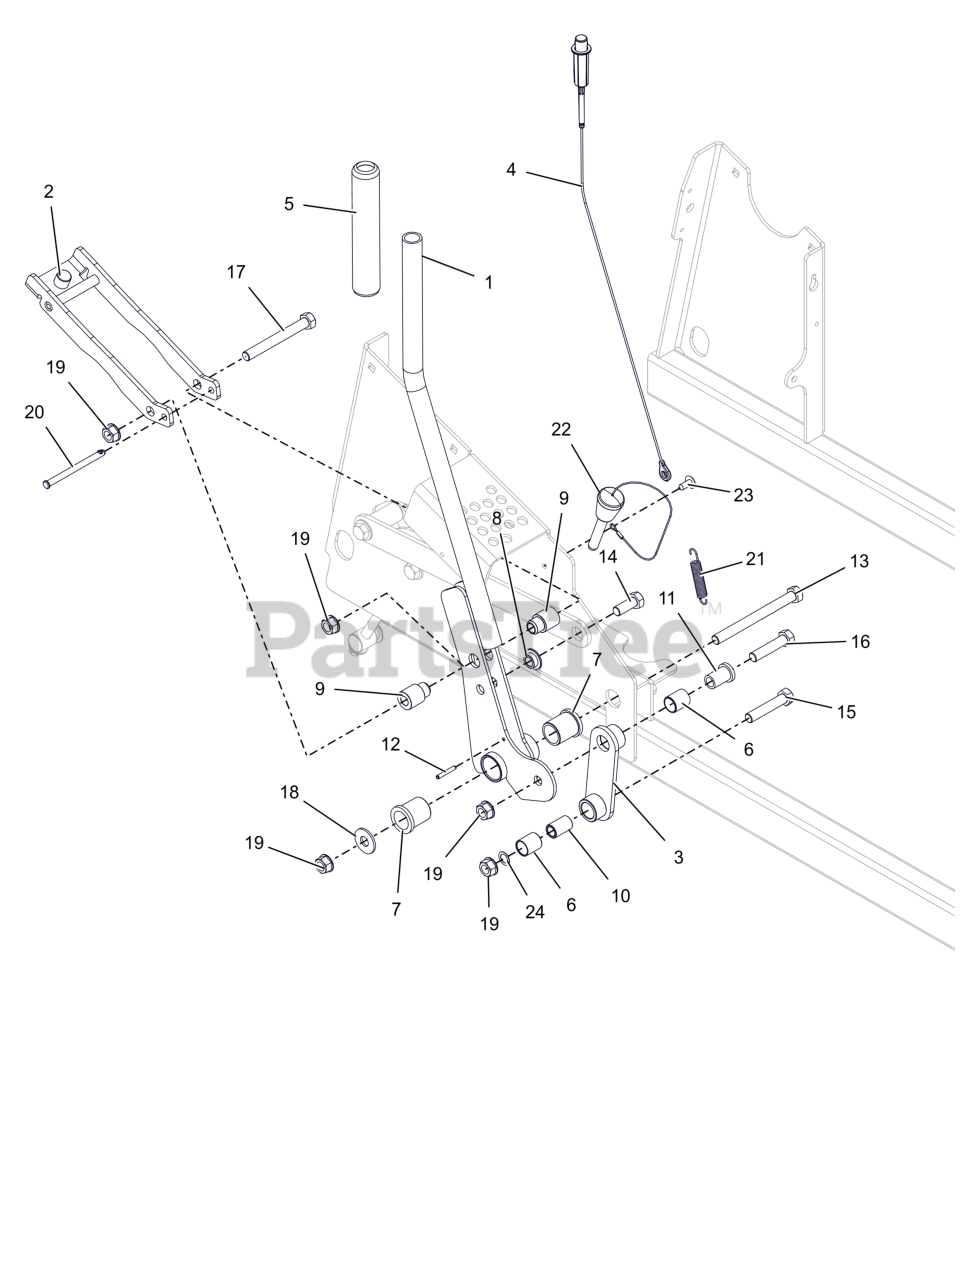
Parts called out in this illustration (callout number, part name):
1	WLDMT, HOC LEVER
2	WLDMT, HOC BRACKET
3	LINK, HOC LEVER
4	CABLE, HOC PUSH CONTROL
5	GRIP, DECK LIFT
6	BRG, .750 X .875 X 1.000
7	BSHG-FLG 1.00X1.25X1.50X1.50
8	BSHG, FLG .515X.750X.360X1.12
9	BSHG,FLG
10	SPCR, SLV .532 X .750 X 1.150
11	BSHG-FLG .515X.746X1.290X1.000
12	PIN-ROLL .188X1.25
13	BLT,HEX .50-13X5.50 G5 ZCC
14	BLT,HEX .50-13X1.25 G5 ZCC
15	BLT, HEX .50-13X2.50 G5 ZCC
16	BLT, HEX .50-13X2.25 G5 ZCC
17	BLT, HEX 0.5-13X4.25 GR5 ZCC
18	WSHR,FLT .563X1.375X.109 ZCC
19	NUT-LK-CTR-FLG .500-13 GG ZCC
20	PIN, SLIC-.3125X4.015X3.625 -ZCC
21	SPRING,EXT,.061X.50X3.0
22	PIN, MAGNETIC .50X2.50
23	XMAS TREE FASTNER-BLACK
24	WASHER, .500X.750X.020 THRUST
